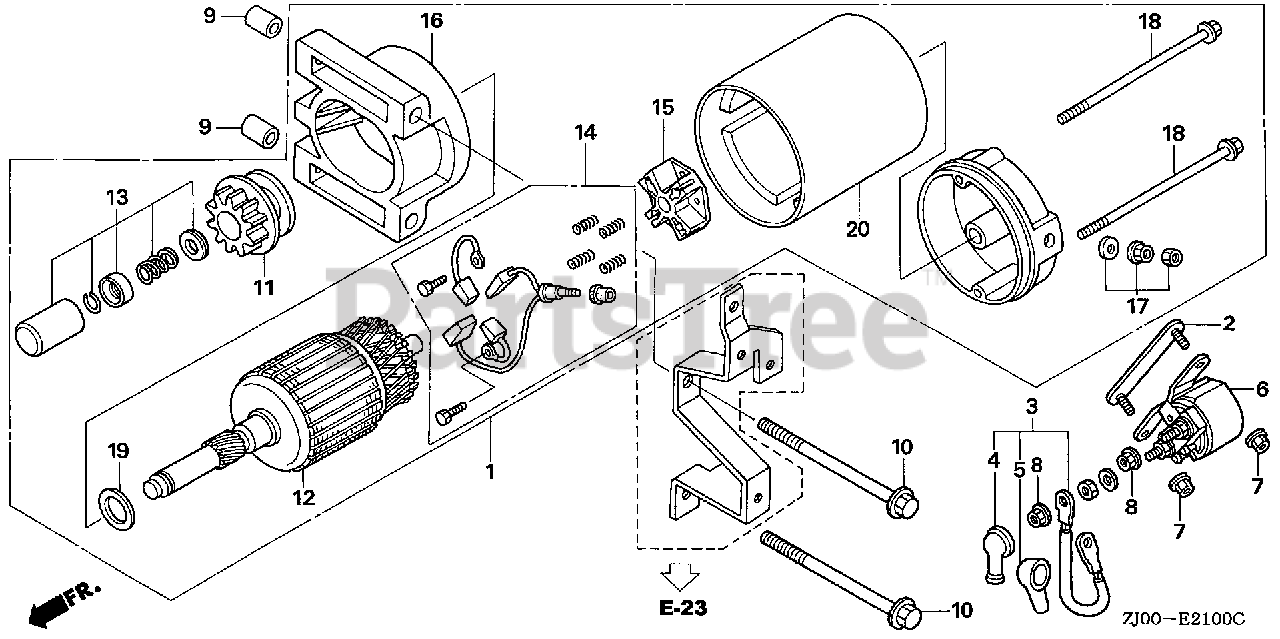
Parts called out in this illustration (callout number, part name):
1	STARTER MOTOR ASSY. (NOT AVAILABLE)
2	BRACKET, STARTER MAGNETIC SETTING
3	WIRE, MAGNETIC SWITCH
4	COVER A, MAGNETIC SWITCH
5	COVER, STARTER MOTOR TERMINAL
6	SWITCH ASSY., STARTER MAGNETIC
7	NUT, FLANGE (6MM)
8	NUT-WASHER (6MM)
9	PIN, DOWEL (10X12)
10	BOLT, FLANGE (8X110)
11	GEAR SET, PINION
13	STOPPER SET, PINION
14	BRUSH SET
15	HOLDER, BRUSH
16	BRACKET, FR.
17	NUT SET, TERMINAL
18	BOLT, THROUGH
19	WASHER, THRUST
